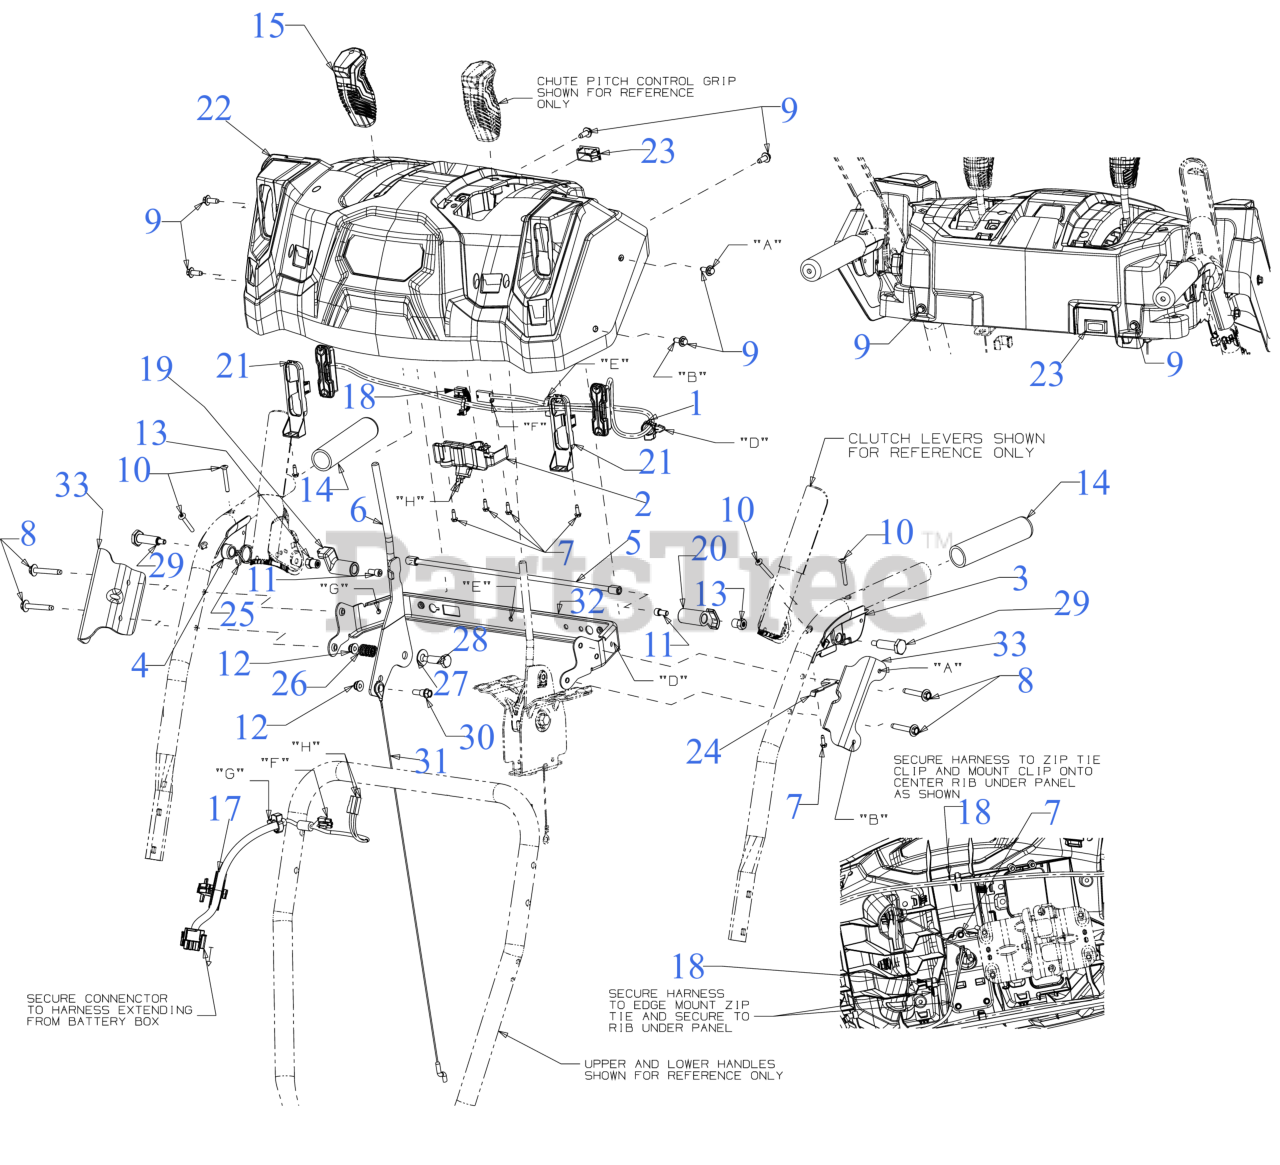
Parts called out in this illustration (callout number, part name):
1	HEADLIGHT HARNESS (W/LED)
2	PUSH BUTTON SWITCH
3	CLUTCH LOCK HANDLE ASSEMBLY (LH)
4	CLUTCH LOCK HANDLE ASSEMBLY (RH)
5	PIVOT ROD
7	SCREW #8-16 x .50
8	SCREW 1/4-20 x 1.625
9	SCREW M6-1 x .625
10	SCREW #10-24 x 1.375
11	SCREW 1/4-20 x .50
12	FLANGE LOCK NUT
13	HEX NUT W/PATCH
17	HARNESS (2S/PBS/HDLT)
18	EDGE MOUNT ZIP TIE CLIP
19	LOCK PLATE
20	CLUTCH LOCK CAM
21	LENS BEZEL
22	PANEL (HDLT/PBTN)
23	SWITCH PLUG
24	CLUTCH SPRING
25	TORSION SPRING
26	COMPRESSION SPRING
27	FLAT WASHER .38X.88
27	FLAT WASHER .401X.88
28	SHOULDER SCREW
29	SHOULDER SCREW .437 x 1.345 1/4-20
30	SHOULDER SCREW .342X.335X1/4-20
31	SELECTION CABLE
